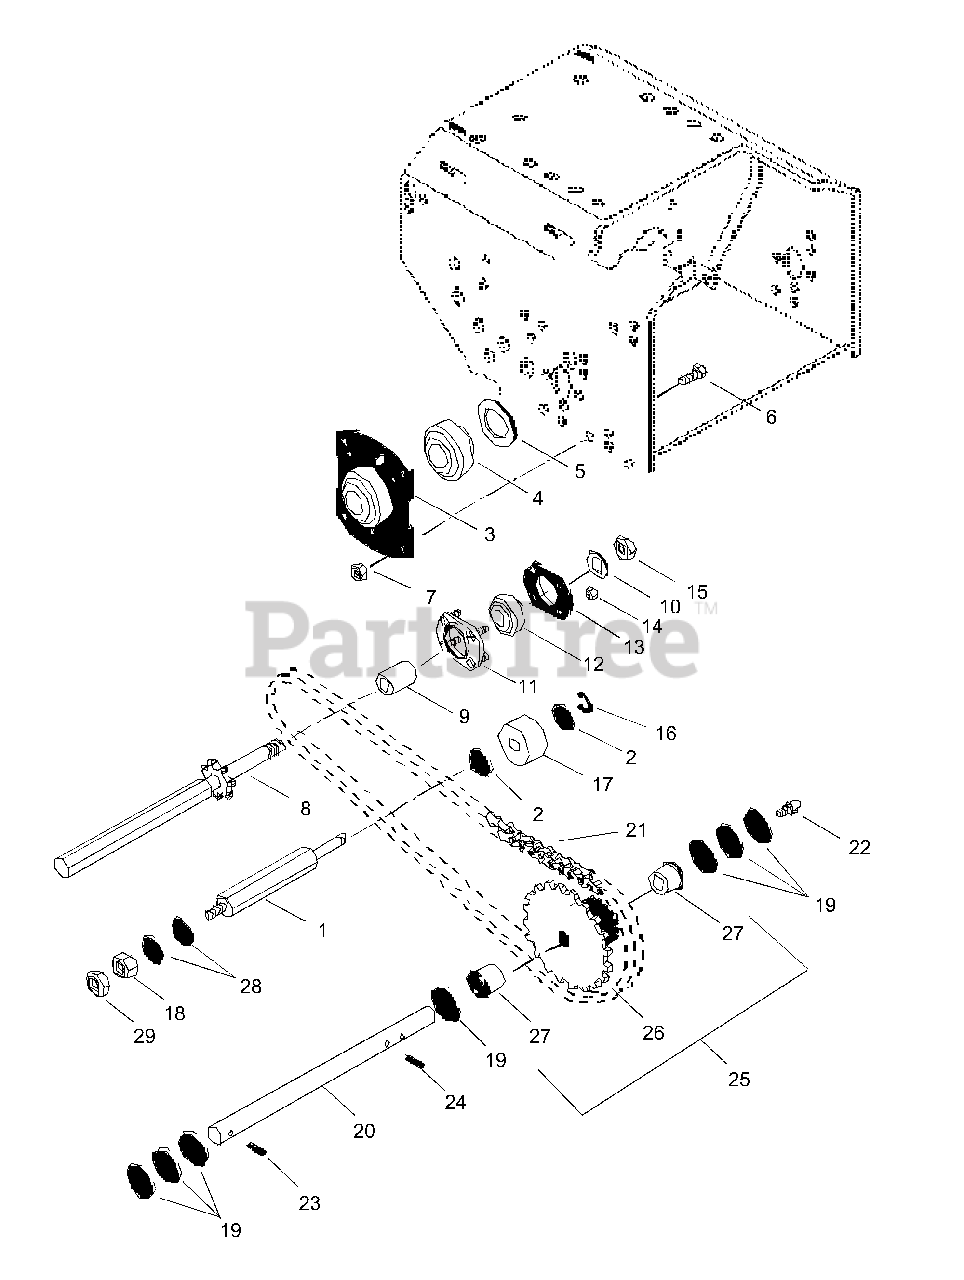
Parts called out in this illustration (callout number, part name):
1	SHAFT, HEX
2	@WSHR-FL-STL.344X.688X.065YWZC
3	BEARING RETAINER
4	BRG-BALL 1.13X2.19X.63
5	WSHR-FL-STL 1.140X1.718X.134YZ
6	BLT-SERNK SL .25-20X.50 YWZC
7	@NUT-SPNLK-FLG .25-20 YWZC
8	SHAFT, HEX - W/SPROCKET
9	BSHG-SLV .450X.750X1.600
10	WSHR-FL-STL .505X.880X.072 YWZ
11	BEARING FLANGE
12	BRG-BALL .437X1.375X.437
13	BEARING FLANGE
14	NUT-LK-DUAL FACE 10-24 YWZC
15	@NUT-LK-CTR .44-14 YWZC
16	RG-RTNG-EXT. .31X.025
17	IDLER 1.38 OD X .31 ID X .69
18	@NUT-LK-CTR .31-18 YWZC
19	WSHR-FL-STL .630X1.005X.062 YZ
20	PINION SHAFT
21	ROLLER CHAIN #41 - 34 PITCHES
22	DRIVE FITTING, HYD. BRIGHT ZC
23	PIN-ROLL .156X1.00
24	PIN-ROLL .125X1.00
25	PINION & SPROCKET ASSEMBLY
26	PINION & SPROCKET
27	BSHG-FLG .625X.750X.500X.875BR
28	@WSHR-FL-STL.38X.875X.083 YWZC
29	NUT- JAM .312-18 YWZC
